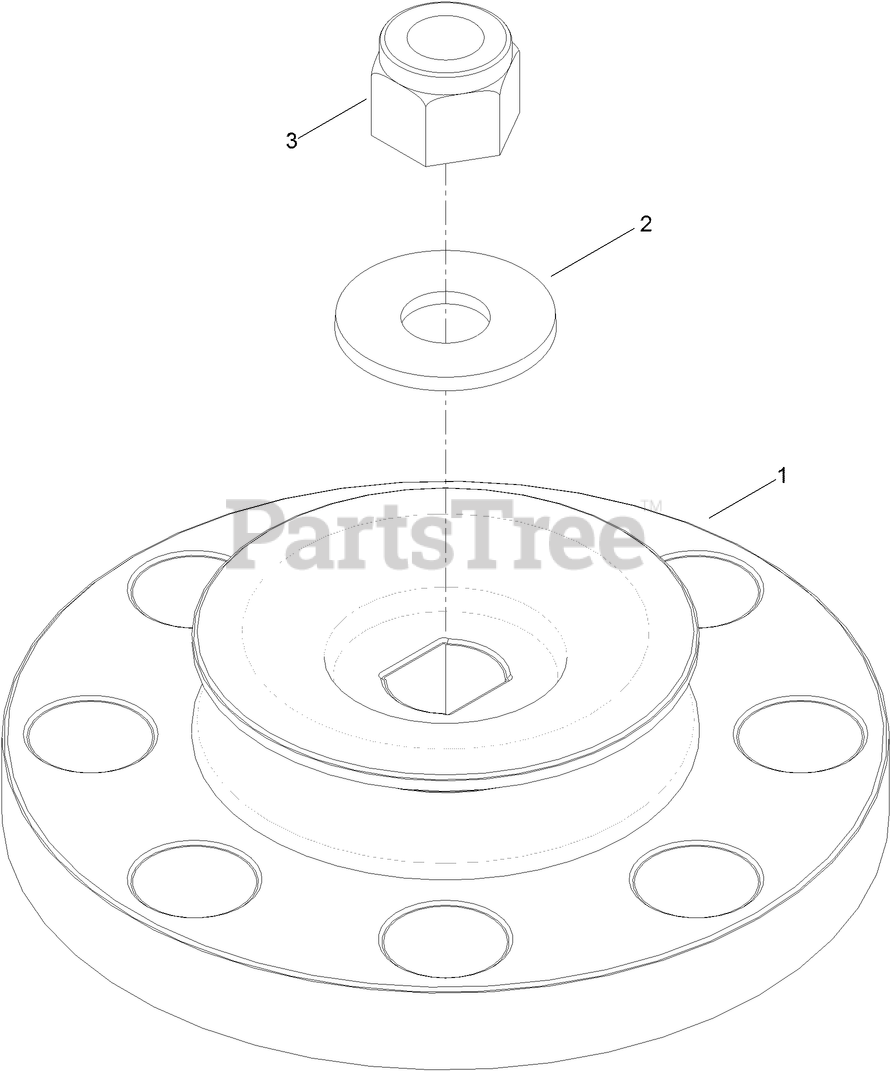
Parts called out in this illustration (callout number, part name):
1	PULLEY-BRAKE, SPINDLE
2	WASHER-SPRING
3	NUT-HEX
